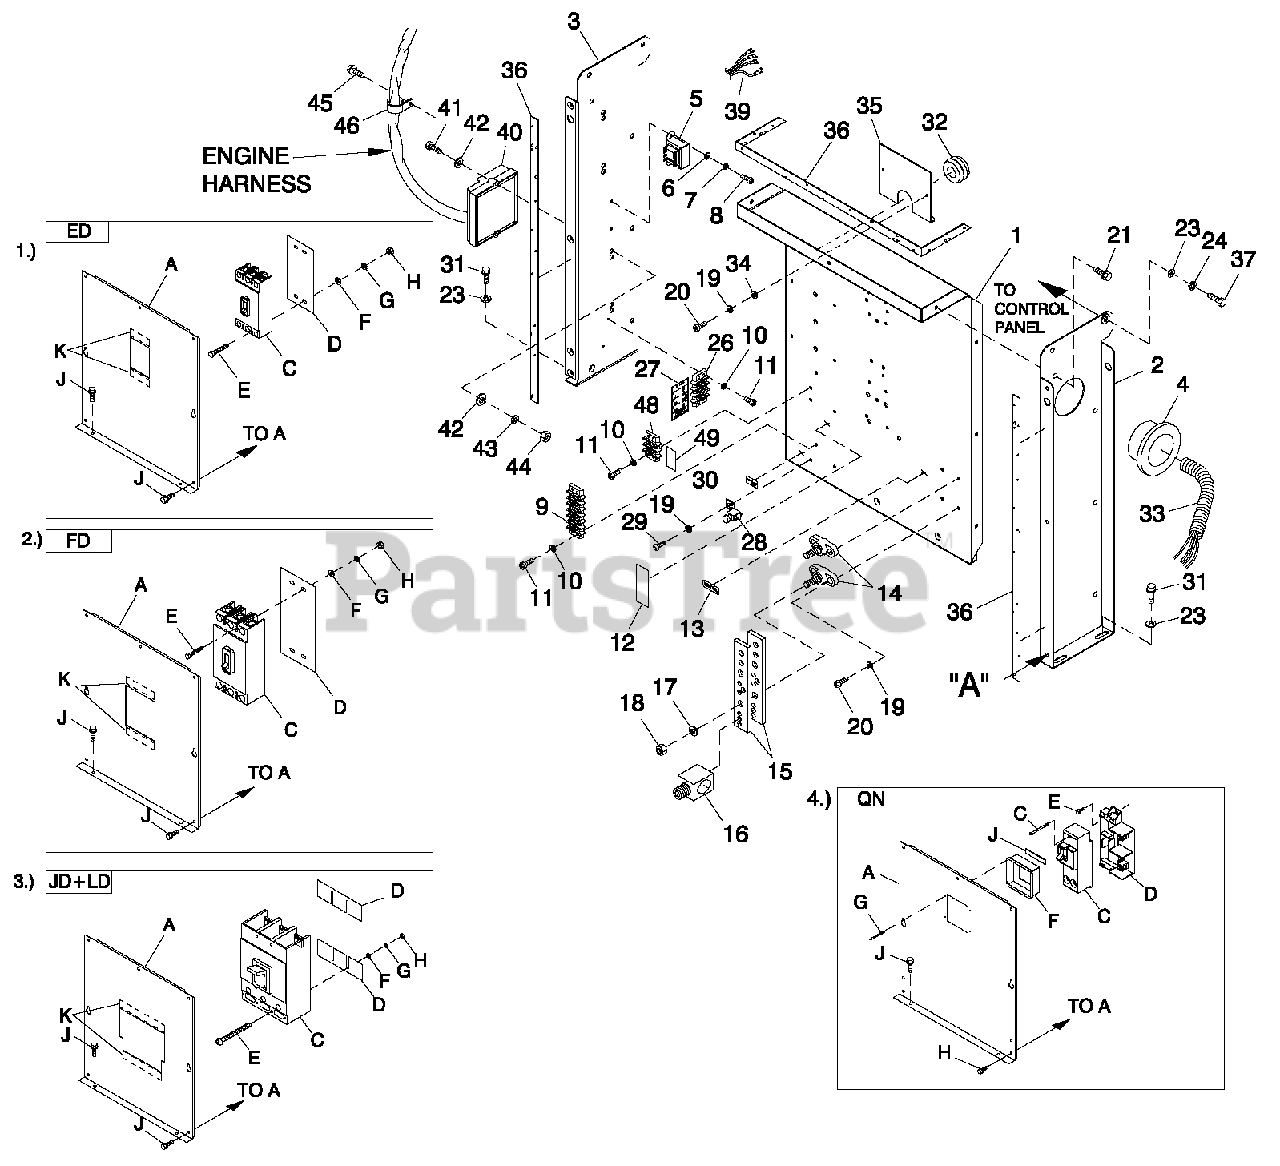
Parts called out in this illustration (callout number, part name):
1	PAN CB CONN BOX
1	UL CIRCUIT BREAKER (ED)
2	STAND RH CONTROL
2	UL CIRCUIT BREAKER (FD)
3	STAND LH CONTROL
3	UL CIRCUIT BREAKER (JD+LD)
4	BUSHING SNAP SB-2.5-31
4	UL CIRCUIT BREAKER (QN)
5	XFMR DUAL 120V/16V (FOR 120/240V & 277/480V UNITS)
6	WASHER FLAT M4
7	WASHER LOCK #8-M4
8	SCREW PHTTM4-0.7X 10 ZYC
9	BLOCK TERM 20A 6 X 6 X 1100V
10	WASHER LOCK #6
11	SCREW PHTT #6-32X1/2 ZYC
12	DECAL RTS CUSTOMERCONNECTION
13	DECAL NEUTRAL
14	JUNCTION BLOCK 3/8-16
15	BUS BAR NEUTRAL BLOCK 390
16	LUG SLDLSS 600/250-1/0 X 1/4-28
17	WASHER LOCK 3/8
18	NUT HEX 3/8-16 STEEL
19	WASHER LOCK M5
20	SCREW PHTT M5-0.8X 16 ZYC
21	SCREW THF M6-1 X 16 N WAZ/JS
23	WASHER FLAT 1/4-M6 ZINC
24	WASHER LOCK M6-1/4
26	BLOCK TERM 20A 6 X 3 X 1100V
27	DECAL CHARGER POWER 120VAC C2
28	LUG SLDLSS #6-14X 13/64 CU
29	SCREW HHTT #10-32X3/8 CZ
30	DECAL GROUND LUG
31	SCREW HHTT M6-1.0X 16ZYC
32	GROMMET 1.25 X .25 X .75
33	CONDUIT FLEX 2.0" ID (36" LG)
34	WASHER FLAT M5
35	PLATE WIRE SNGLGALV
36	TAPE ELEC 1/2 FOAM (AS REQ'D)
37	SCREW HHC M6-1.0X 16 G8.8
39	HARNESS, TRANSFORMER ADAPTER
40	PCB ENCLOSURE ASSY 4.2L IGN MD
41	SCREW PPHM #10/32X2
42	WASHER FLAT #10 ZINC
43	WASHER LOCK #10
44	NUT HEX #10-32 STEEL
45	SCREW THF M6-1 X 16 N WAZ/JS
46	CLAMP VINYL 1.06 X.406Z
47	SEAL WEATHER .45" DIA
48	BLOCK TERM 20A 2 X 6 X 1100V
49	DECAL GTS CUSTOMER CONNECTION
A	COVERED CB SHORT STND
C	CB0050A3P 480V SED 4 LL
D	INSULATOR CBS(ED-3P)
E	SCREW RHM #10-32X4-1/2
F	WASHER FLAT #10 ZINC
G	WASHER LOCK #10
H	NUT HEX #10-32 STEEL
J	SCREW THF M6-1 X 16 N WAZ/JS
K	TAPE ELEC 1/2 FOAM (AS REQ'D)
A	COVER CB CONN BOX
C	CB0150A3P 600V SFD6 LL
D	INSULATOR CB FD FRAME 30MIL
E	SCREW SHC 1/4-20 X 4.5 G8.8 NZ
F	WASHER FLAT 1/4-M6 ZINC
G	WASHER LOCK M6-1/4
H	NUT HEX 1/4-20 STEEL
J	SCREW THF M6-1 X 16 N WA Z/JS
A	COVER JD/LD CB SHRT STAND
C	CB 0300A 3P 600V S JD6 LL
D	INSULATOR CIRCUIT BR. JD/LD
E	SCREW RHM 1/4-20X3
A	COVER QN FRM C B
C	CB 0150A 2P 240V S QN2 LL
D	BASE, QN CIRCUIT BREAKER
E	SCREW HHTT M5-0.8X 10 BP
F	COVER Q N C B DISH
G	RIVET POP .125X.275SS
H	SCREW THF M6-1X16 N WA Z/JS
J	TAPE ELEC 1/2 FOAM (AS REQ'D)
